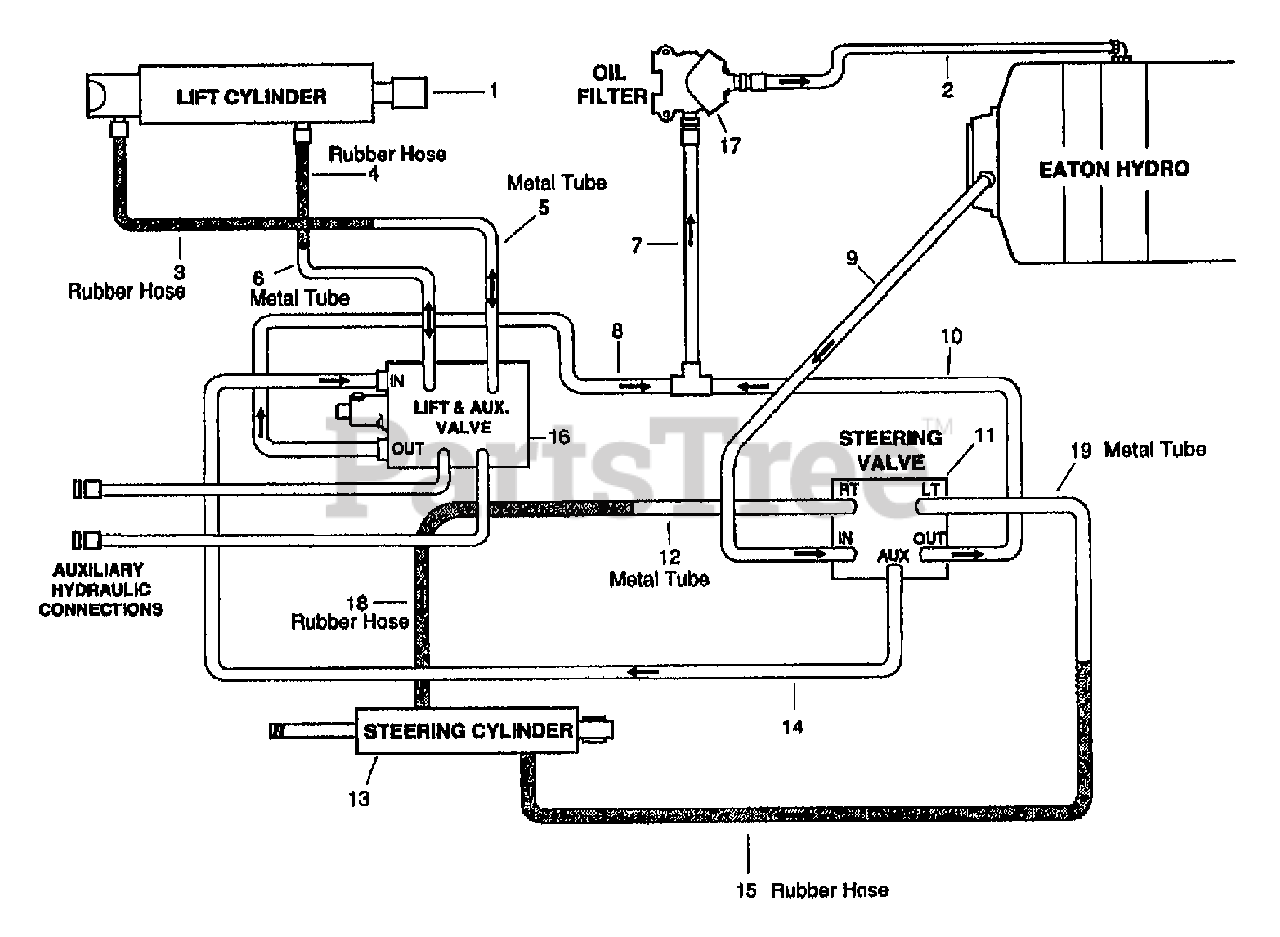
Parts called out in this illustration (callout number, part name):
1	LIFT-CLYINDER
2	ASSM-RETURN TUBE
3	ASSM-HOSE
4	ASSM-HOSE
5	ASSM-TUBE
6	ASSM-TUBE
7	ASSM-TUBE
8	ASSM-TUBE
9	ASSM-TUBE
10	ASSM-TUBE
11	KIT-STEERING VALVE
12	ASSM-TUBE
13	CYLINDER-HYDRAULIC
14	ASSM-TUBE
15	ASSM-HOSE
17	FILTER-OIL
18	ASSM-HOSE
19	ASSM-TUBE
